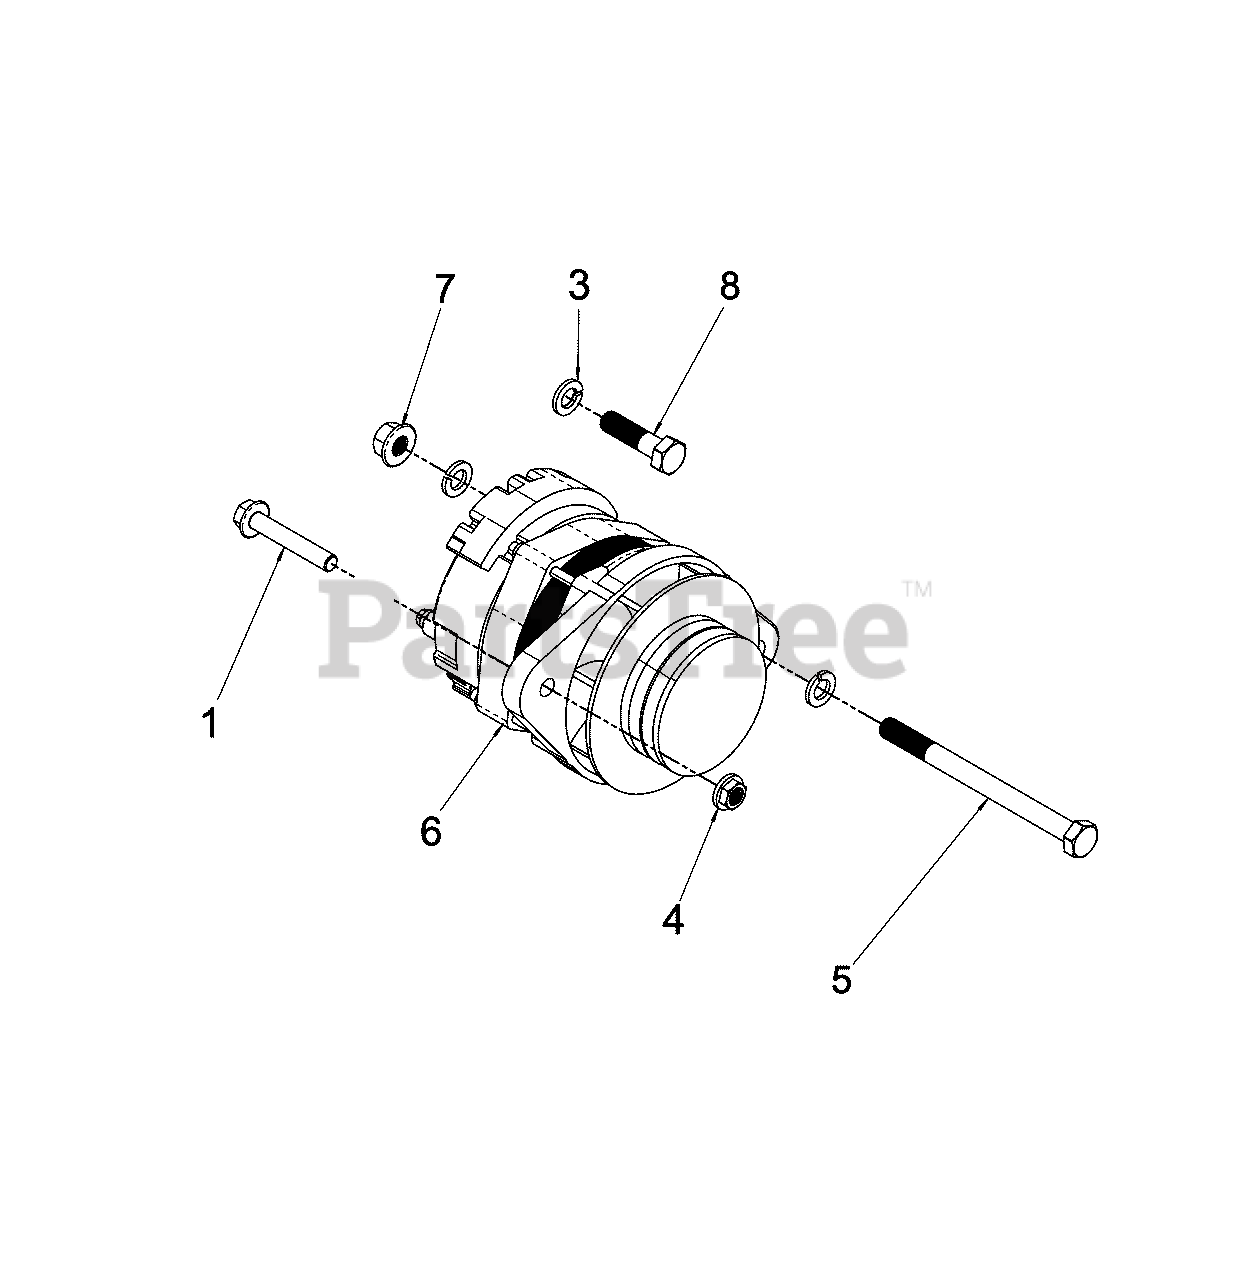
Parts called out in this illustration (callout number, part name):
1	* BOLT
3	* WASHER
4	* NUT
5	* BOLT
6	ALTERNATOR
7	* NUT
8	* BOLT
